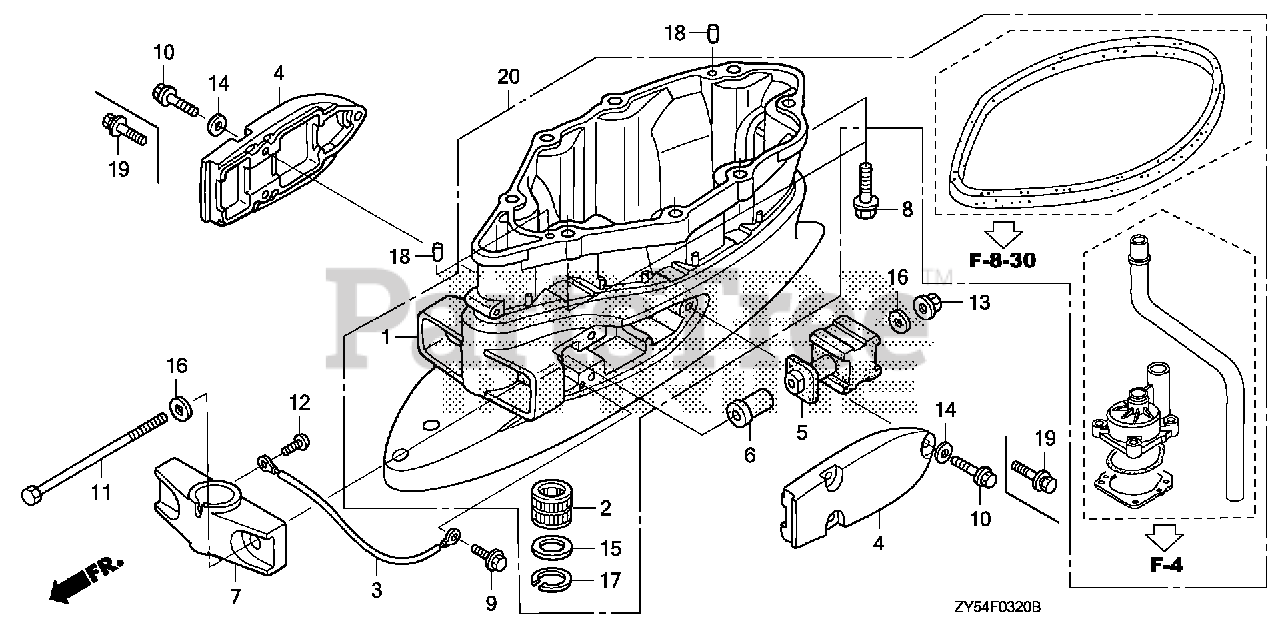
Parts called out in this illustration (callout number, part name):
1	CASE KIT, EXTENSION *NH282MU* (OYSTER SILVER METALLIC-U)
1	CASE, EXTENSION *NH282MU* (OYSTER SILVER METALLIC-U)
2	BUSH, VERTICAL SHAFT
3	WIRE, LEAD (1.5X137MM)
4	HOUSING, MOUNTING (LOWER) *NH282MU* (OYSTER SILVER METALLIC-U)
5	RUBBER, MOUNT (LOWER)
6	COLLAR, MOUNTING (LOWER)
7	HOUSING, CENTER MOUNTING (LOWER) *NH282MU* (OYSTER SILVER METALLIC-U)
8	BOLT, FLANGE (10X40)
9	BOLT, FLANGE (6X12)
11	BOLT, HEX. (12X225)
12	SCREW, PAN (6X8)
13	NUT, FLANGE (12MM)
15	WASHER (26MM)
16	WASHER, PLAIN (12MM)
17	CIRCLIP (INNER) (40MM)
18	PIN, DOWEL (6X10)
19	BOLT-WASHER (8X30)
20	CASE KIT, EXTENSION *NH282MU* (OYSTER SILVER METALLIC-U)
